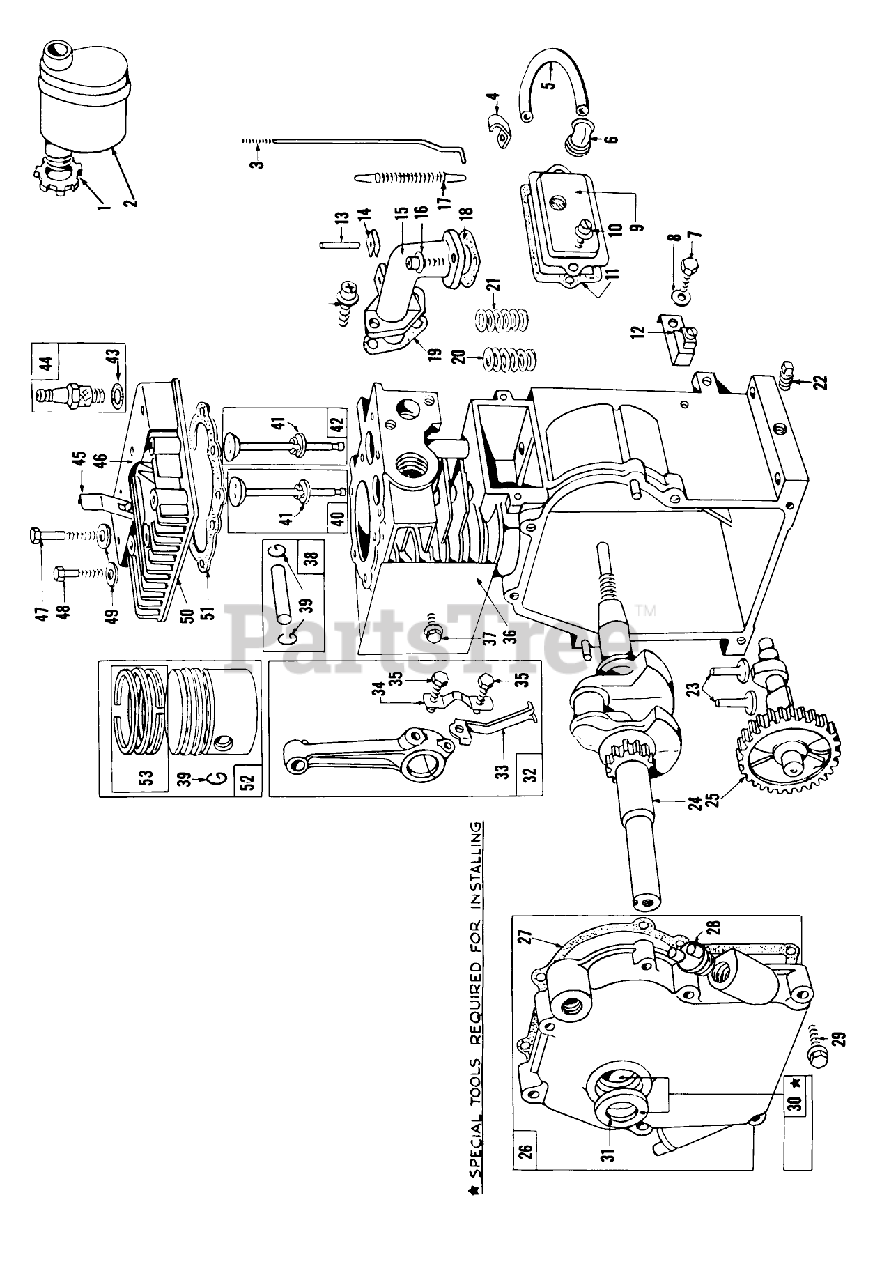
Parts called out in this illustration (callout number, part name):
1	Locknut-Muffier
2	Muffler-Exhaust
3	Rod-Control
4	Support, Tube
5	Tube, Breather
6	Grommet
7	Screw, Sem
8	Washer-Plain
9	Breather-Valve Chamber
10	Screw, Breather Mtg. Stem
11	Gasket Breather
12	Bracket, Control Wire Casing
13	Stop, Control Rod
14	Clip-Control Rod
15	61762/95-5929-5 WHE
16	Screw, Carburetor and Intake Elbow Mounting Stem
17	Spring-Governor
18	Gasket-Carburetor
19	Gasket-Carburetor
20	1531A GIL 3 1/2HP T
21	Spring-Valve
22	Plug-Pipe
23	Tappet-Valve
24	Crankshaft
25	Gear-Cam
26	Cover Assy.-Crankcase
27	Gasket-Crankcase" thick (Standard)
28	Plug-Oil
29	Screw
30	Bushing
31	Seal-Oil
32	Rod Assy.-Connecting
33	Dipper-Conn. Rod
34	Lock, Conn Rod Screw
35	Screw, Conn.Rod
36	Muffler-Exhaust
37	Screw
38	Pin Assy., Piston, Standard
39	Iock-Piston Pin
40	Valve Exhaust
41	Gear-Cam
42	Valve Intake
43	Gasket-Spark Plug
44	Plug, Spark (with Gasket)
45	Switch-Stop
46	Cover-Cylinder Head
47	Screw, Cylinder Head
48	Screw-Cylinder Head
49	Washer
50	Head-Cylinder
51	Gasket-Cylinder Hd.
52	Piston Assy., Standard
53	Ring Set-Standard Piston Consists of: No. 210796 Ring, Piston, Compression, Top, Std. No. 210797 Ring, Piston, Compression, Ctr, Std. No. 295661 Ring, Oil (w/expander) Std.
